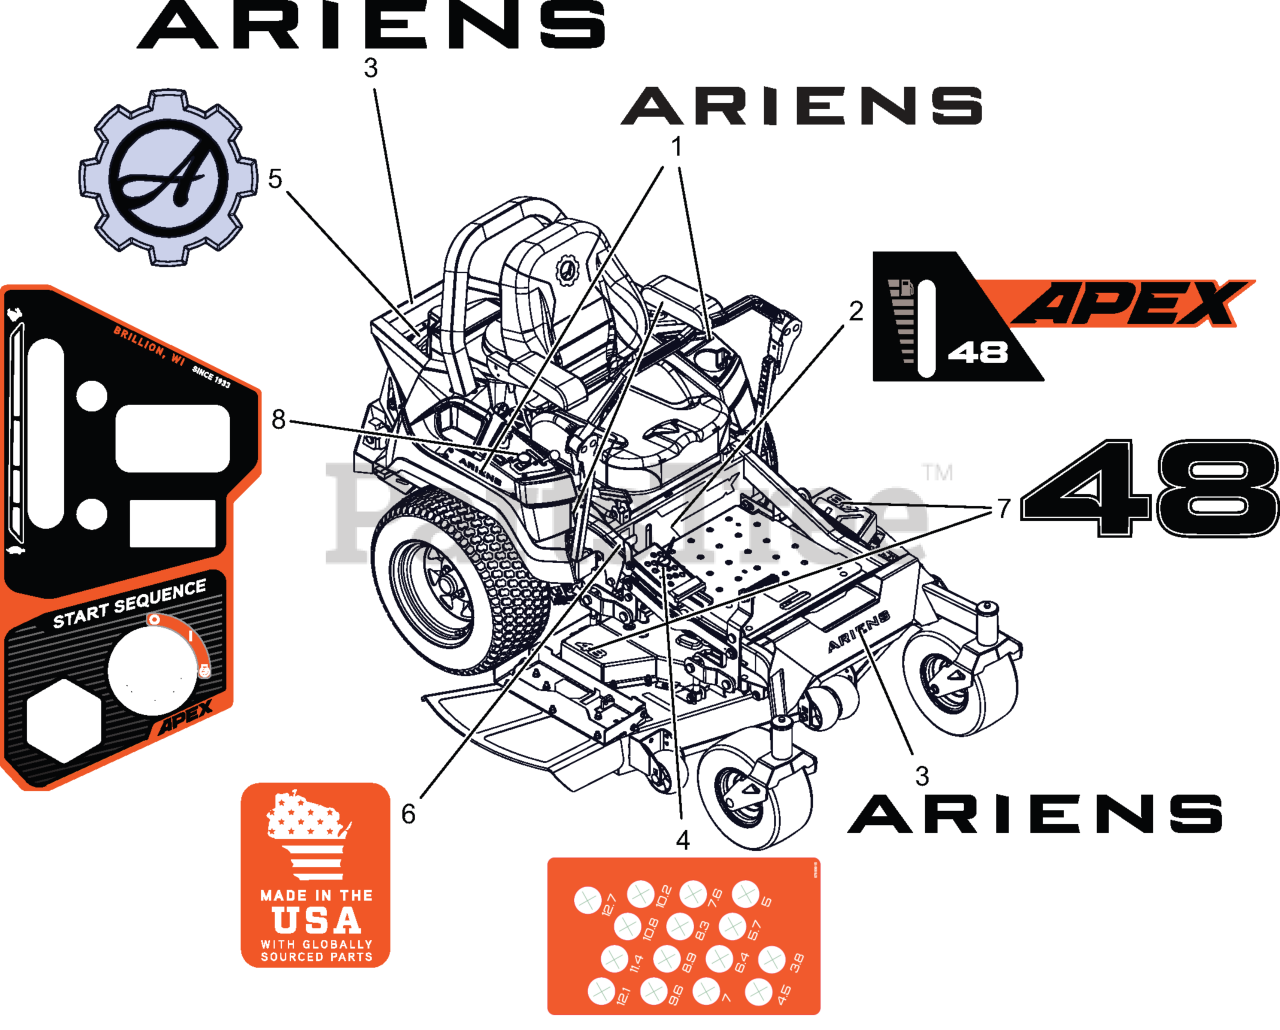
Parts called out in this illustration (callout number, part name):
1	DECAL- ARIENS 6.000" BLACK
2	DECAL- APEX 48 KICKPLATE
3	DECAL- ARIENS 9.625" BLACK
4	DECAL, APEX HOC METRIC
5	DECAL- ARIENS GEAR BADGE
6	DECAL- MADE IN USA
7	DECAL- DECK 48
8	DECAL- DASH -APEX & ZENITH
